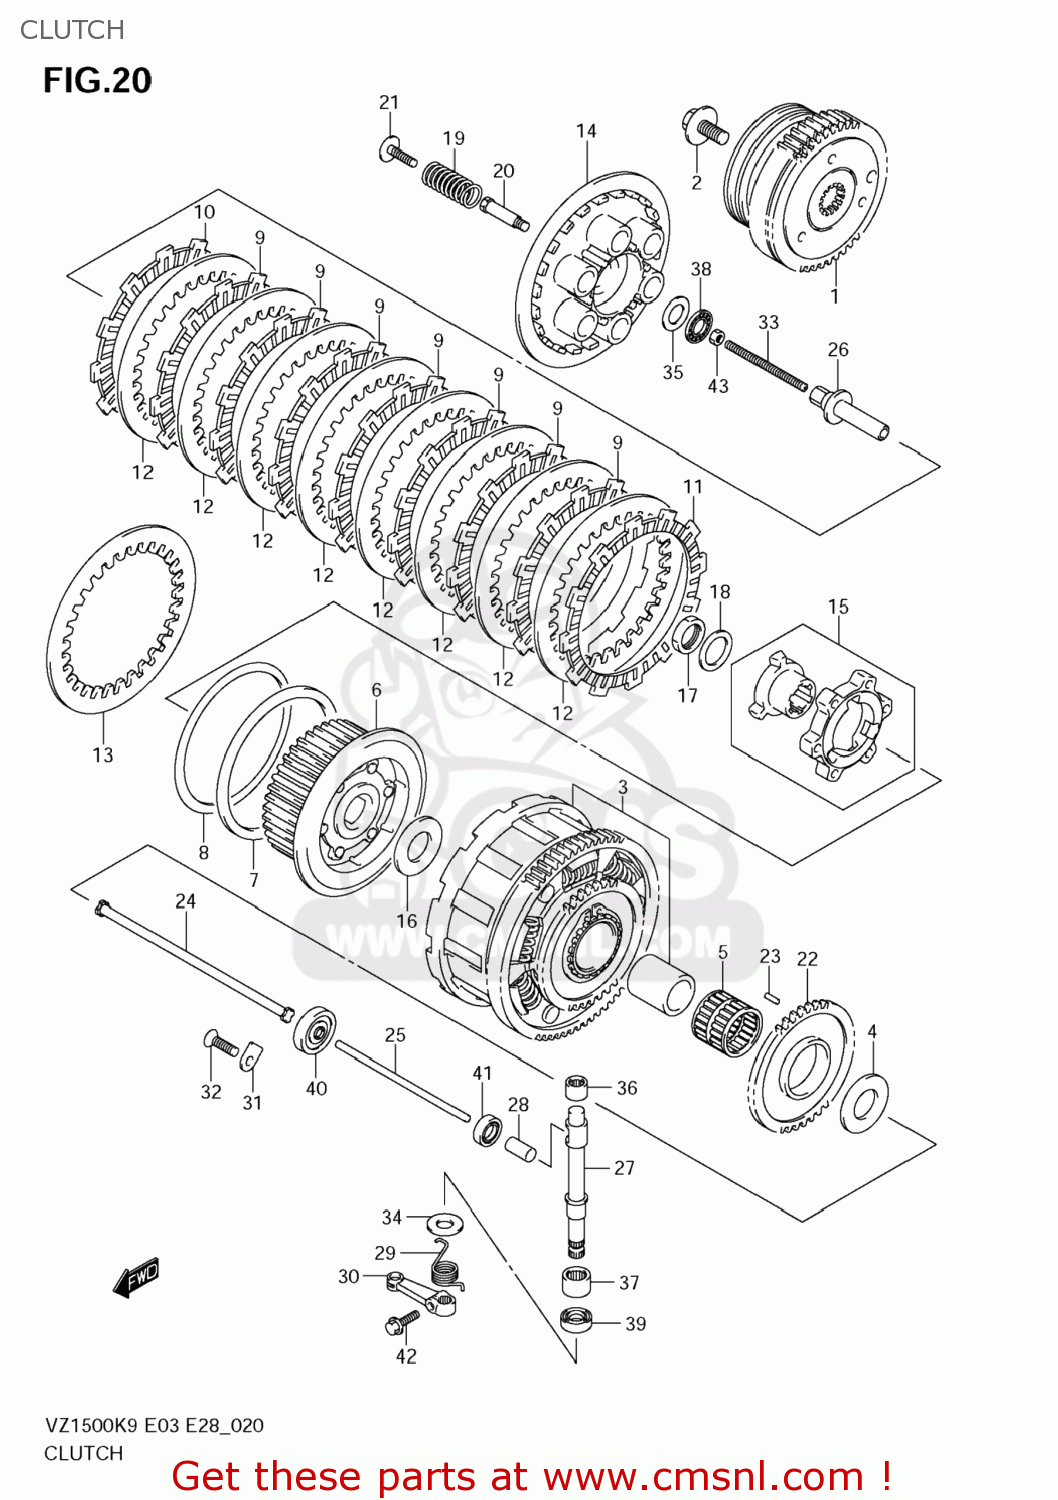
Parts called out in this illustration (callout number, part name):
1	GEAR,PRIMARY DRIVE SET
2	BOLT(14X28)
3	GEAR ASSY,PRI DRIVEN
4	WASHER(25X52X2.5)
5	BEARING(35X40X39.8)
6	HUB,CLUTCH SLEEVE
7	SEAT,WAVE WASHER
8	WASHER,CLUTCH PLATE WAVE
9	PLATE,CLUTCH DRIVE NO.1 (NAS)
10	PLATE,CLUTCH DRIVE NO.2 (NAS)
11	PLATE,CLUTCH DRIVE NO.3 (NAS)
12	PLATE,CLUTCH DRIVEN NO.1(T:2.0 (NAS)
13	PLATE,CLUTCH DRIVEN NO.2(T:2.3 (NAS)
14	DISC,CLUTCH PRESSURE
15	CAM SET,CLUTCH
16	WASHER(25X50X3.5)
17	NUT
18	WASHER
19	SPRING,CLUTCH
20	BOLT,CLUTCH SP
21	BOLT,CLUTCH SPRING
22	GEAR,OIL PUMP DRIVE
23	PIN(4X15.8)
24	ROD,CLUTCH
25	ROD,CLUTCH PUSH,L
26	PIECE,CLUTCH PUSH
27	CAMSHAFT,CLUTCH
28	CAP,CLUTCH PUSH ROD
29	SPRING,CLUTCH RELEASE RETURN
30	ARM,CLUTCH RELEASE
31	RETAINER,COUNTER BEARING,R
32	SCREW(6X12)
33	SCREW(6X73)
34	WASHER(10.5X24X1)
35	WASHER(15.5X28X1)
36	BEARING(10X14X10)
37	BEARING(12X18X12)
38	BEARING(15X28X2)
39	SEAL,OIL(10X20X6)
40	SEAL,OIL(6X18X5)
41	SEAL,OIL(10X17X5)
42	BOLT
43	NUT
